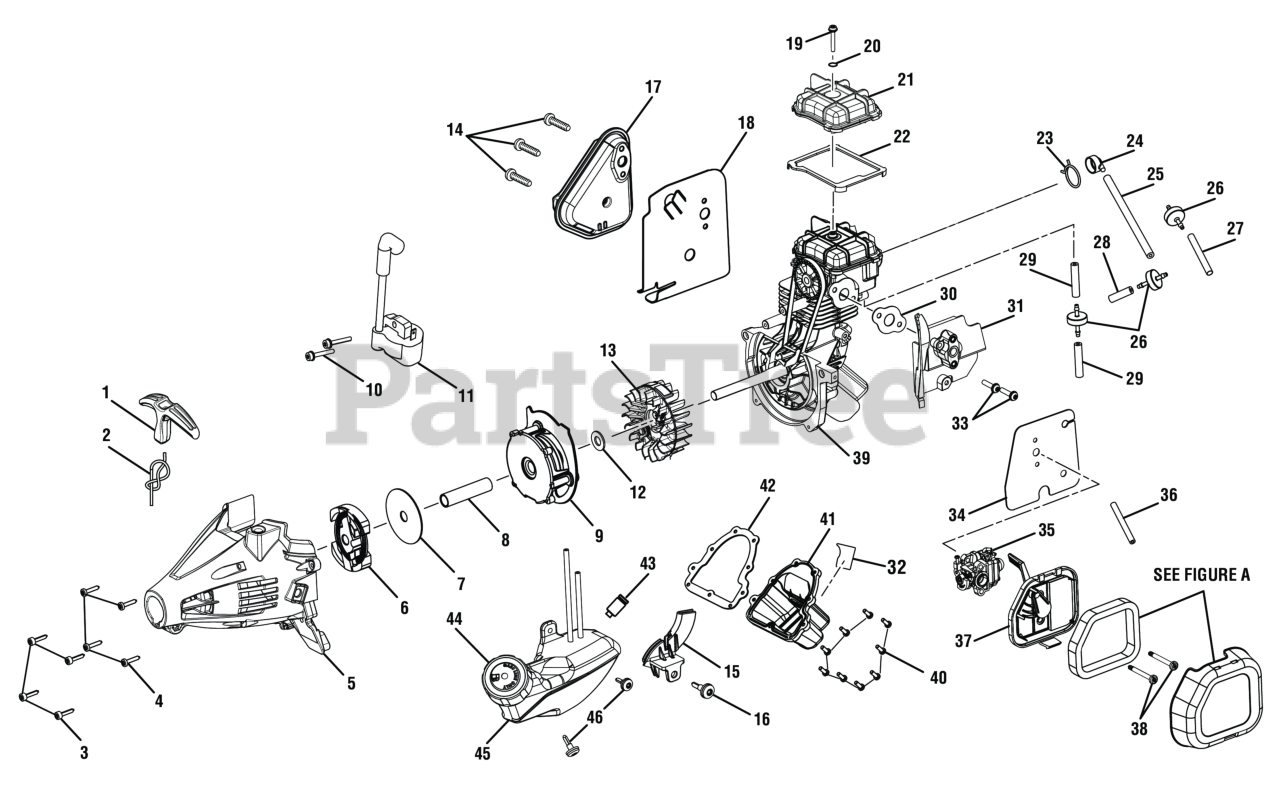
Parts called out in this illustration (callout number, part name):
1	Pulley Handle
2	STARTER ROPE 42 (PKG)
3	Screw (M4 x 18 mm, T20 Torx Pan Hd. S.T.)
4	Screw w/Washer (M4 x 16 mm, T25 Torx Truss Hd.)
5	Starter Housing Assembly
6	CLUTCH ASSEMBLY
7	Washer (ID9.63 x OD50.75 x 1.10t)
8	Spacer Tube
9	Starter Housing Assembly
10	Screw w/Washer (M4 x 19 mm, T20 Torx Pan Hd. S.T.)
11	Ignition Module
12	Washer (ID9.75 x OD20 x 1.6t)
13	Flywheel Assembly
14	Screw (M5 x 38 mm, T25 Torx Truss Hd.)
15	Throttle Cable Guide
16	Shoulder Screw (M4 x 19 mm, T25 Torx Truss Hd.)
17	Muffler Assembly
18	Muffler Gasket
19	Screw (M4 x 27 mm Total, w/14 mm Threaded)
21	Cam Cover
22	Cam Cover Gasket
23	Wire Clamp
24	Breather Fitting
25	Breather Hose (120 mm)
26	Check Valve
27	Shield Sleeve (M6 x 50 mm)
28	Breather Hose (24 mm)
29	Breather Hose (34 mm, Crankcase)
30	Heat Dam Gasket
31	Heat Dam
32	Hot Surface Label
33	Screw (M5 x 23 mm, T25 Torx Pan Hd.)
34	Heat Shield w/Gasket (Carburetor)
35	Carburetor
36	Breather Hose (50 mm)
37	Air Box Base Assembly
38	Screw (M5 x 44 mm,T25 Torx Hd. Carburetor)
39	Short Block Assembly
40	Screw (M4 x 12 mm, T20 Torx Hd.)
41	Oil Pan (Inc. Key No. 47)
42	Oil Pan Gasket
43	Fuel Filter
44	Fuel Cap Assembly
45	Fuel Tank w/Cap (Inc. Key Nos. 43-44)
46	Shoulder Screw w/Washer (M4 x 14 mm, T25 Torx Truss Hd.)
